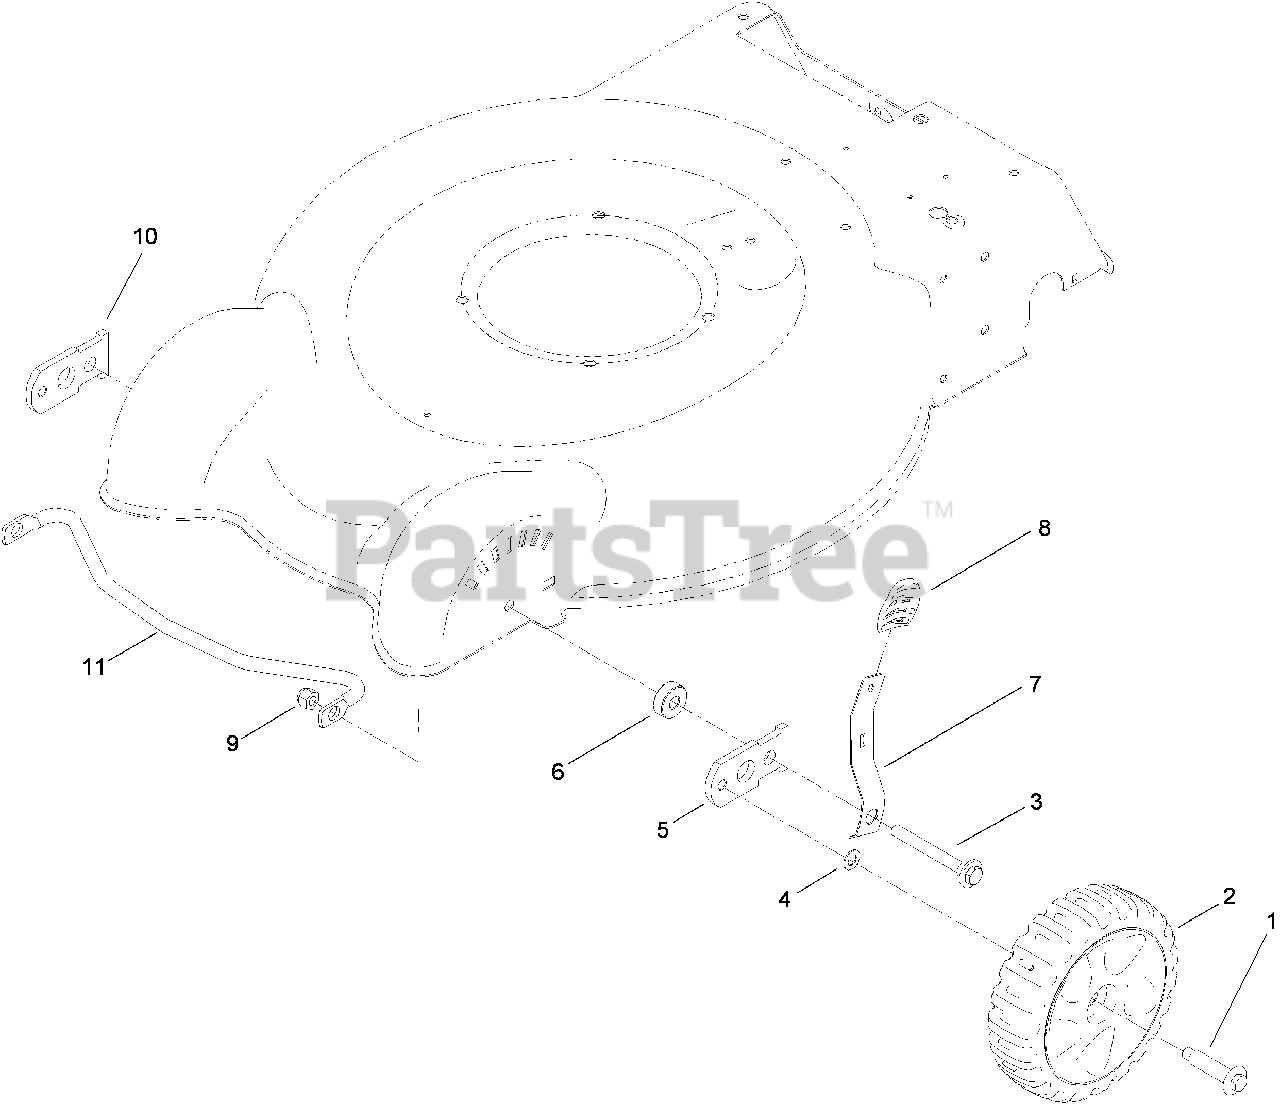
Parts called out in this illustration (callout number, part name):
1	BOLT-SHOULDER
2	7 INCH FRONT WHEEL ASM
3	BOLT-SHOULDER
5	ARM-PIVOT, RH
6	SPACER-ARM, PIVOT
7	ARM-SPRING, FRONT
8	Knob-Lever, HOC
9	NUT-LOCK, NI
10	ARM-PIVOT, LH
11	BRACE-FRONT
